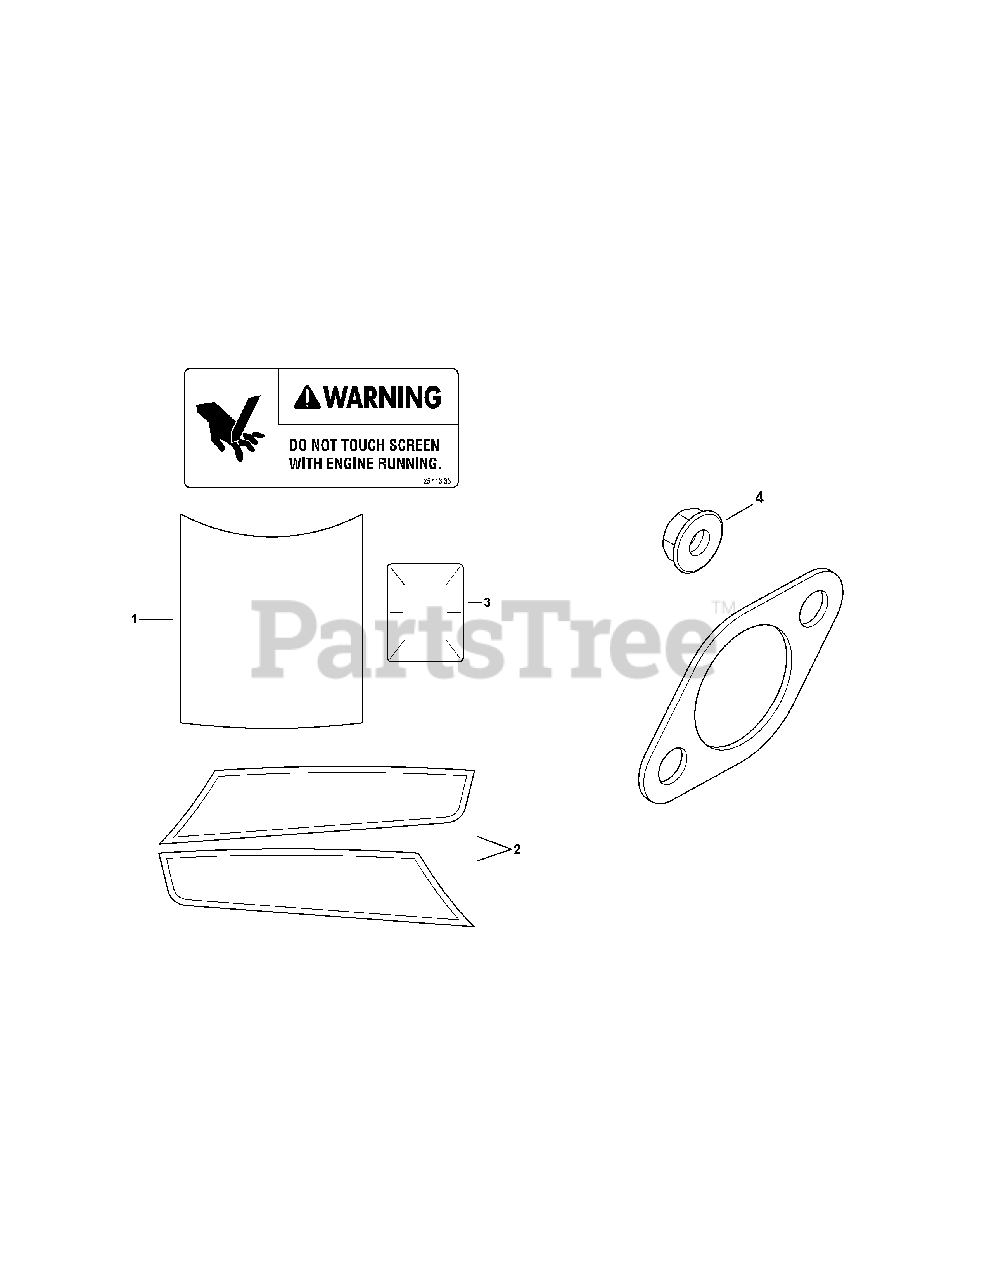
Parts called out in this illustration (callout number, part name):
2	Wing Set Decal
3	Clear Laminate Decal
4	Flange Nut, 1/4-20
